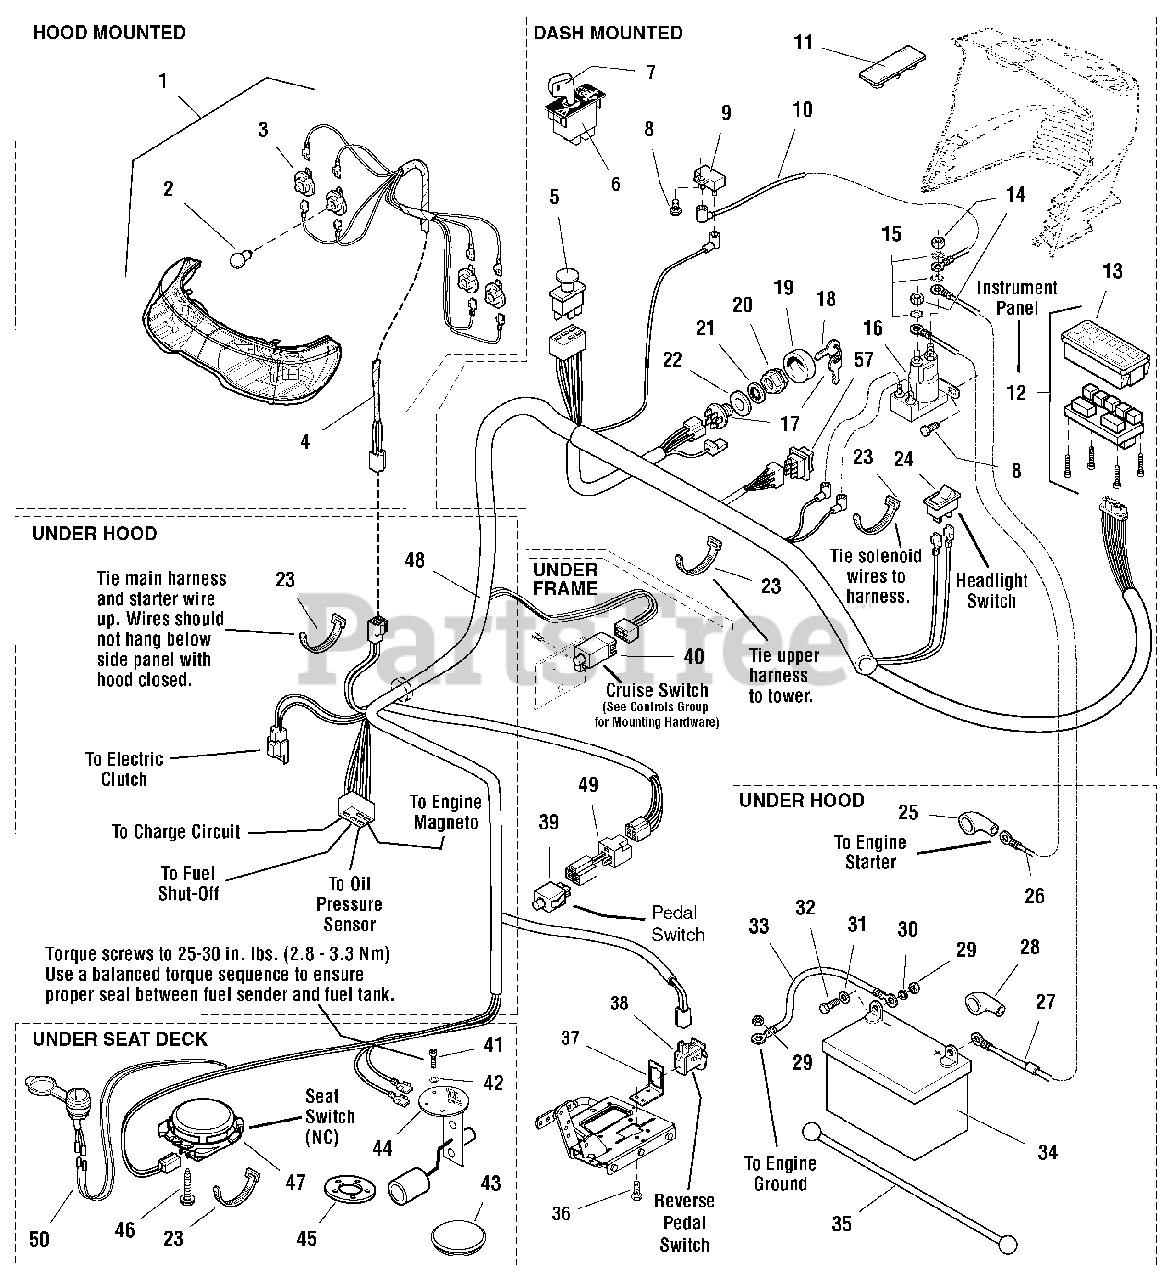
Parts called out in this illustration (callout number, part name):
1	HEADLIGHT ASSEMBLY, 4 Bulb
2	BULB, Headlight, 12.8V
3	SOCKET ASSEMBLY, Headlight, Sealed
4	HARNESS, Headlight
5	SWITCH, PTO Push/Pull Symbols
6	SWITCH, RMO Module Only
7	KEY, RMO Module Plastic
8	CAPSCREW, Hex Washer Head Taptite, 1/4-20 x 1/2, Black
9	BREAKER, Circuit, 12 Volt 20 Amps
10	WIRE, 12GA 5-15/16 Long, Red
11	PLUG, Hole, Square
12	PANEL, Instrument w/ Fuel Gage & Hour Meter
13	COVER, Instrument Panel
14	NUT, Hex, 5/16-24
14	NUT, KEPS Lock 5/16-24
15	LOCKWASHER, External Tooth, 5/16
16	SOLENOID
17	SWITCH ASSEMBLY, Ignition, 6 Pin INDAK
18	KEYS, Set of 2
19	COVER, For Ignition Switch, Plastic
20	NUT, Hex Flange, 5/8-32, Ignition Switch
21	LOCKWASHER, Internal Tooth, 5/8, Thin
22	WASHER, Shim
23	TIE, Strap, 7-5/16 Long
24	SWITCH, Headlights , 2 Terminal
25	BOOT, Insulator Cable Terminal, 1-15/16 Long, Red
26	CABLE, #6 x 25" Long, Ring Terminals
27	CABLE, #6 x 8" Long, Ring Terminals
28	BOOT, Insulator Battery Terminal
29	NUT, Hex, 1/4-20
30	LOCKWASHER, 1/4
31	WASHER, 1/4
32	CAPSCREW, Hex Head, 1/4-20 x 3/4
33	CABLE, #6 x 26 Long, Ring Terminal
34	BATTERY, 12 Volt
35	STRAP, Battery, 14 Long, Rubber
36	CAPSCREW, Hex Head Taptite, 1/4-20 x 3/8
37	BRACKET, Switch Mount
38	SWITCH, Reverse Pedal
39	SWITCH, Push Button, Foot Pedal
40	SWITCH, Cruise Control, Grey, NO
41	SCREW, Pan Head Torx, #10-32 x 1/2
42	LOCKWASHER, 3/16 #10
43	PLUG, Hole 3", Round
44	SENDER, Fuel Tank
45	GASKET
46	CAPSCREW, Hex Washer Head Plastite, 1/4 x 1/2
47	SWITCH, Seat, Grey, NC
48	HARNESS, Wiring
49	WIRING ASSEMBLY, All Conditions Shutdown
50	12-VOLT OUTLET
57	SWITCH, EHOC
